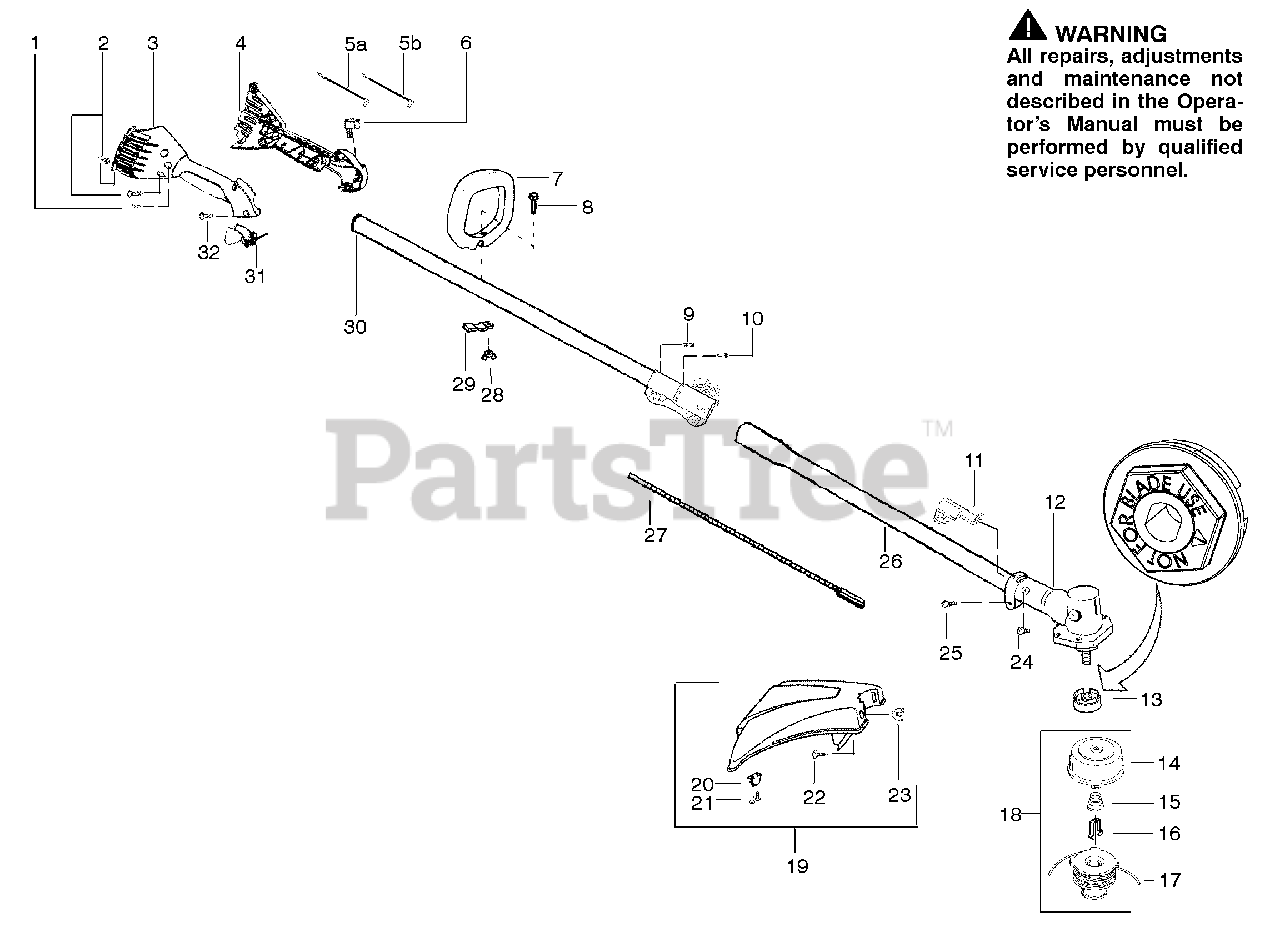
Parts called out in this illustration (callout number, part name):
1	Screw-alignment
3	Throttle hsg-right
4	Kit-Left throttle hsg
5A	Wire Assy-Front Wire
5B	Wire Assy-Front Wire (Upper)
6	Kit-Switch
7	Assy-Handle
10	Screw-Align
11	Bracket-Shield
12	Kit-Gearbox
13	Dust cup
14	Assy-Hub/Arbor
15	Spring-Return
16	Retainer-Spool
17	Accy-Wound Spool
18	Accy-Cutting Head
19	Kit-Shield Assy.
20	Limiter-Line
21	Screw
23	Wingnut
26	Assy-Lower Shaft
27	Shaft-Flex (lower)
28	Wingnut
29	Clamp-Handle
30	Kit-Upper Shaft
31	Lever-Throttle
